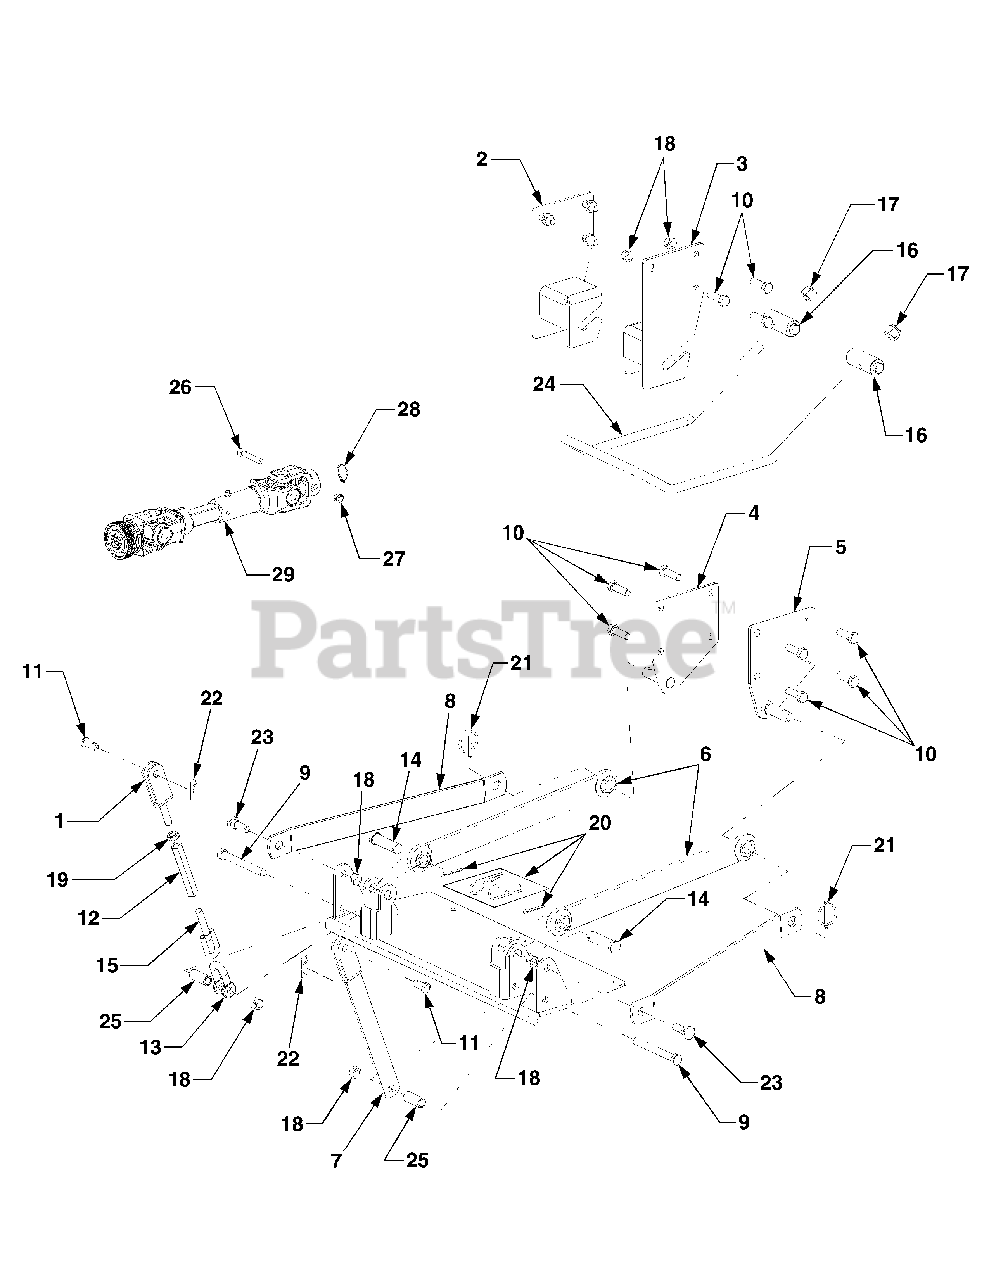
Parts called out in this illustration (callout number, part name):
1	Clevis, Adjustment, 1/2 -13 x 4.76
10	Screw, Hex Cap, 1/2-13 x 1.5 GR5
11	Pin, Clevis, .5 x 1.18
12	Turn Buckle, Hex Adjustment
13	Clevis, Check Chain
14	Pin, Clevis, 3/4 x 2.5
15	Clevis, Chain
16	Pin, Hanger Rod Mounting
17	Nut, Hex Insert Lock, 5/8-11
18	Nut, Hex Center Lock, 1/2-13
19	Nut, Hex Jam, 1/2-13 GR5
20	Pin, Cotter, 3/16 x 1.5
21	Pin, Klik
22	Pin, Internal Cotter
23	Screw, Shoulder, .625 x.36: 1/2-13
24	Rod, Front Hanger
25	Spacer, .52 x .87 x 1.57
26	Screw, Socket Hex, 5/16-18 x 1.75
27	Nut, Hex Insert Lock, 5/16-18
28	Ring, Retaining
29	Shaft, Drive
